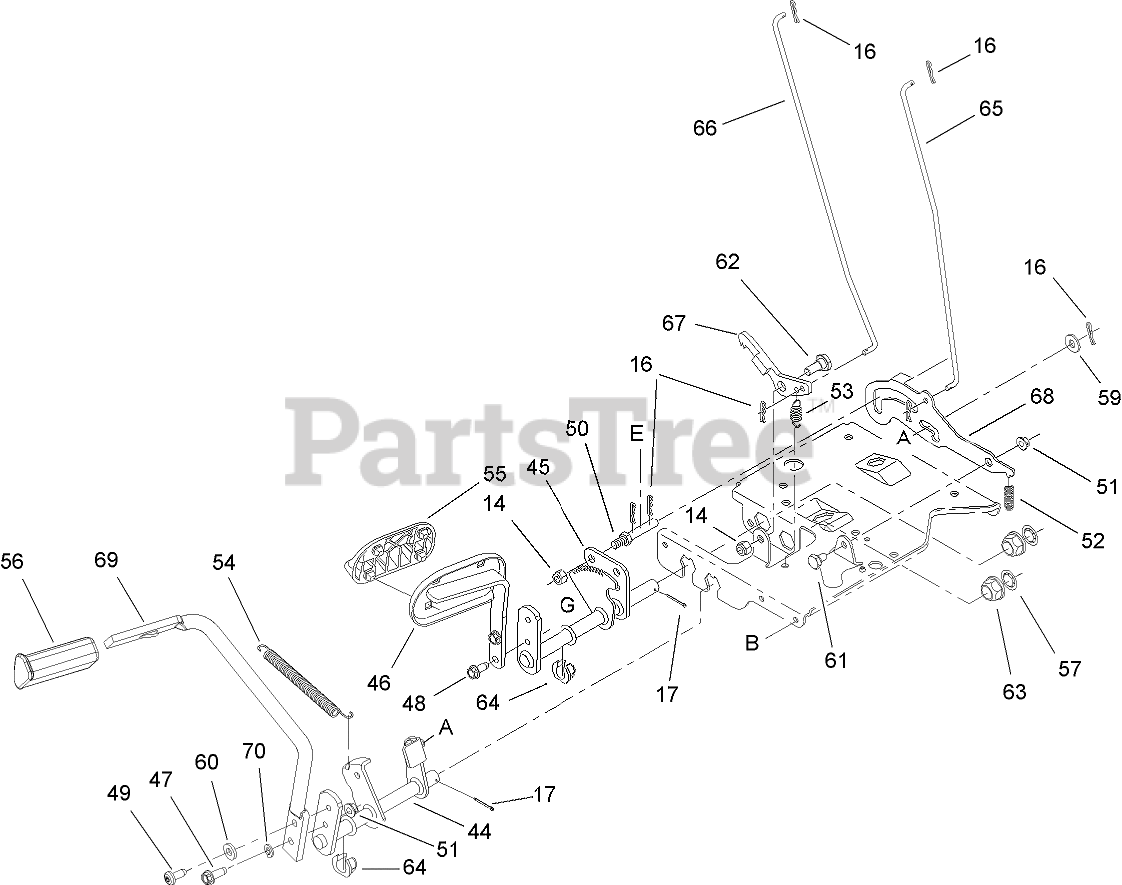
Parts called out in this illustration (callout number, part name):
14	NUT-LOCK, FLANGE
16	PIN-COTTER
17	PIN-COTTER
44	BRAKE CONTROL ASM
45	SPEED CONTROL ASM
46	PEDAL ASM
47	SCREW-HWHTF
48	SCREW-HWH
49	SCREW-TAP
51	NUT-LOCK, FLANGE
52	SPRING
53	SPRING-EXTENSION
54	SPRING-EXTENSION
55	PAD-PEDAL
56	PAD-BRAKE
57	WASHER-FLAT
59	WASHER-FLAT
60	WASHER-FLAT
61	BOLT-SHOULDER
62	BOLT-SHOULDER
63	BEARING-FLANGE
64	BEARING-FLANGE, HEX (SPLIT)
65	ROD-BRAKE, LOCK CONTROL
66	ROD-CONTROL, CRUISE
67	LATCH-CRUISE
68	BRACKET-LOCK OUT
69	PEDAL-BRAKE
70	WASHER-LOCK
